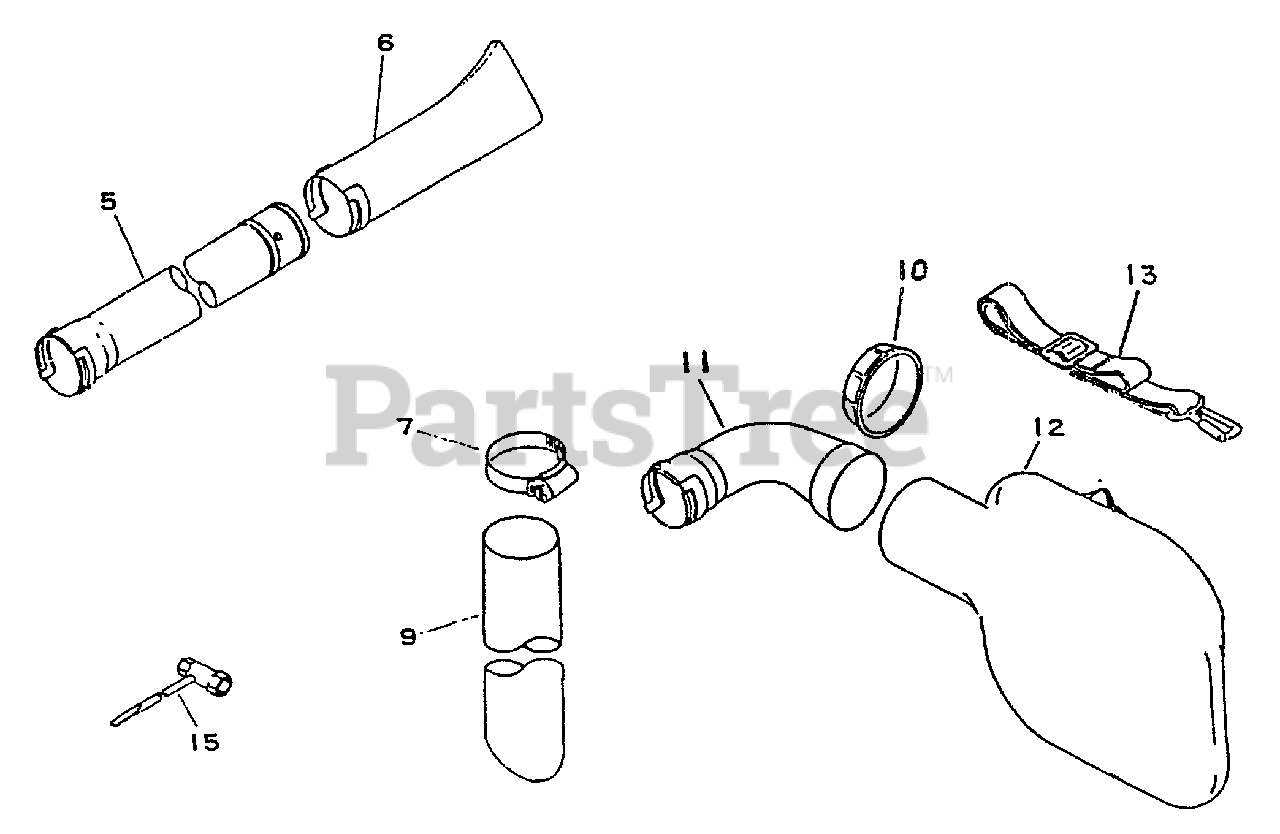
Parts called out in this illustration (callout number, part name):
5	TUBE, BLOWER - STRAIGHT
6	NOZZLE - FAN HEAD
9	ADAPTER, TUBE
12	BAG, DUST
15	T-WRENCH 13×19×180
